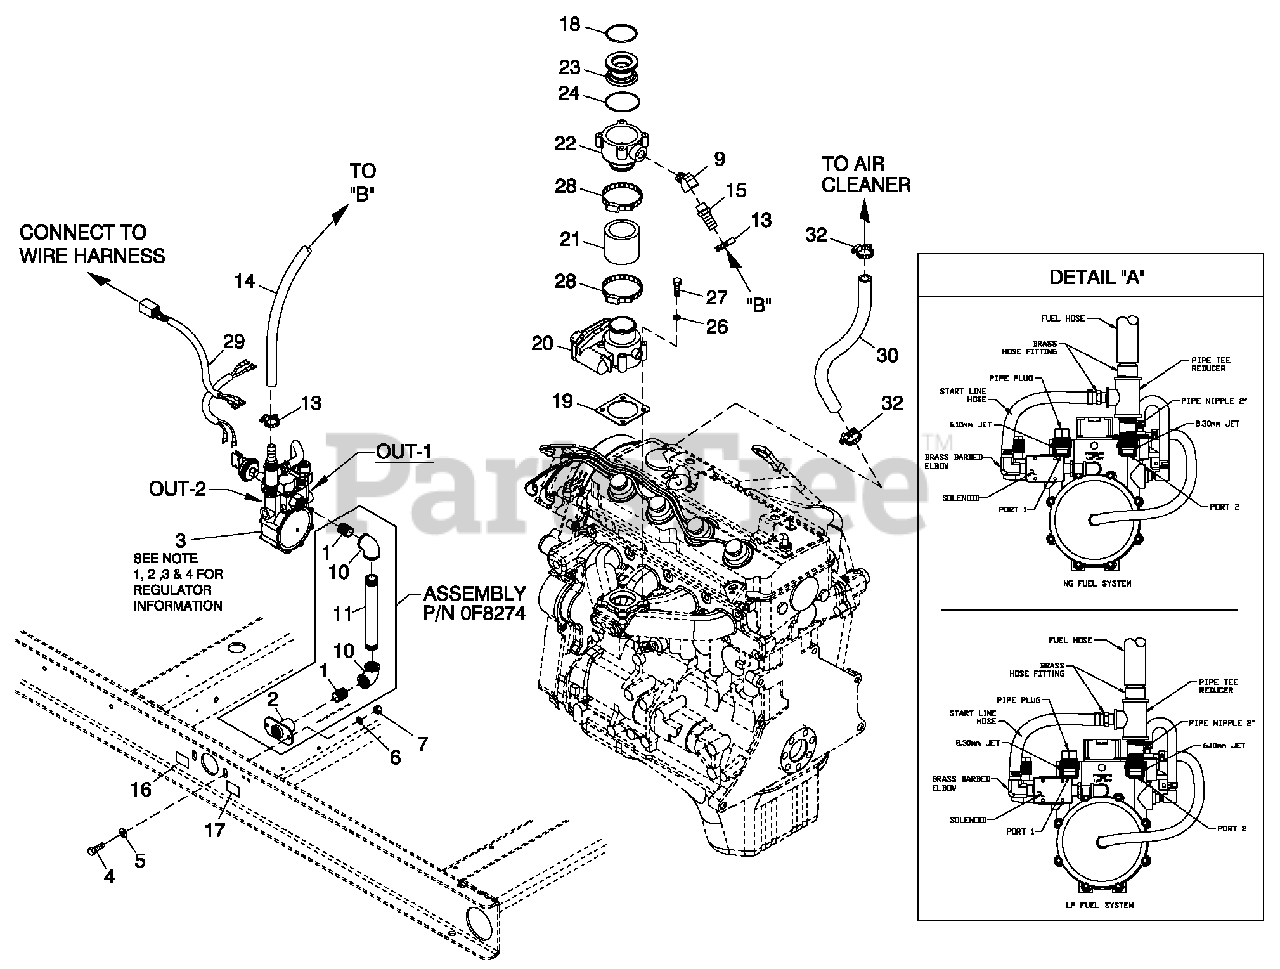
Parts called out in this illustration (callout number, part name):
1	NIPPE COSE 3/4X1.375
2	FANGEFUEINET
3	REGUATOR ASSY 2.4 (25KW)
4	SCREW HHC M8-1.25X 20 G8.8
5	WASHER FAT 5/16-M8 ZINC
6	WASHER OCK M8-5/16
7	NUTHEXM8-1.25G8CEARZINC
9	STREETE45D1/2NPTBRASS
10	EBO 90D3/4NPT
11	NIPPEPIPE3/4NPTX7
13	CAMP HOSE #10 .56-1.06
14	HOSE 3/4 ID SAE-30R2 (18" G)
15	BARBEDSTR1/2NPTX3/4
16	DECAINETPRESSURE
17	DECAFUEINETNG(NATURAGASAPPICATION)
18	O-RING45.63IDX2.62 IDTH
19	GASKETBOSCH32
20	ACTUATORBOSCH40GOVERNOR(45K )
21	HOSECOO2INID20R4(45K )
22	MIXERACTUATOR32MMMACHINED(25K )
23	VENTURITHROTTE26MM(35&45K )
24	O-RING47.625IDX2.38 IDTH
26	WASHER OCK M6-1/4
27	SCREW SHC M6-1.0 X 45 G12.9
28	CAMPHOSE#281.32-2.25
29	HARNESS CP FUE JUMPER
30	HOSE3/8IDSINGEBRAID(18"G)
32	CAMPHOSE#10.56-1.06
